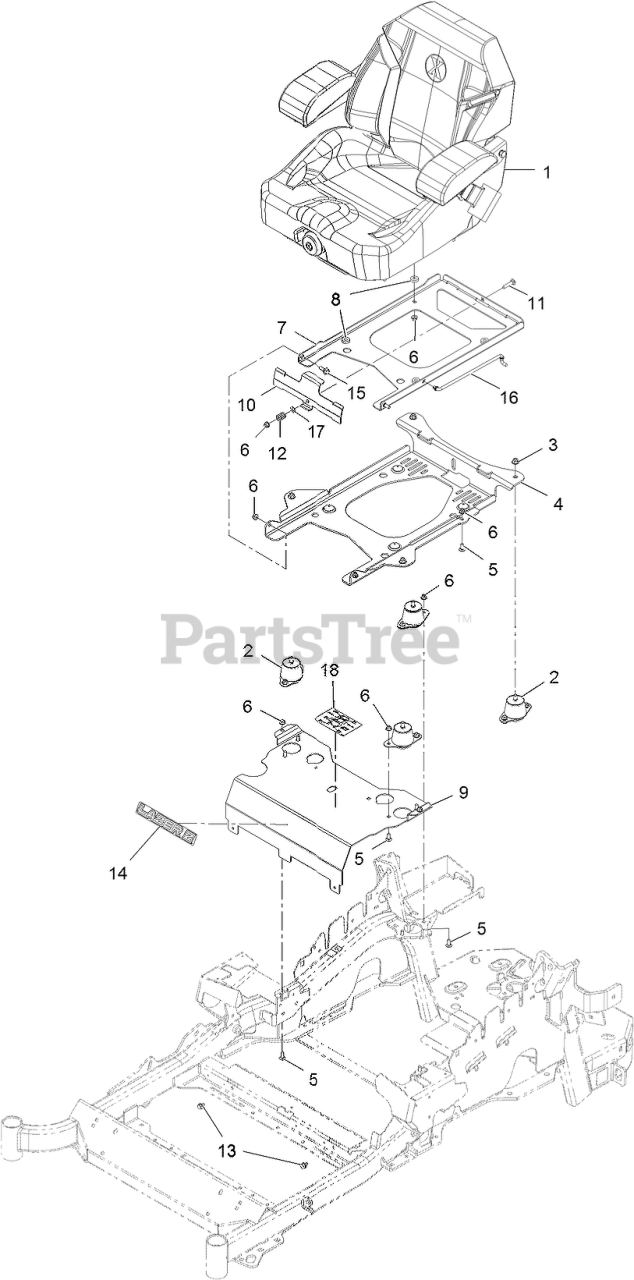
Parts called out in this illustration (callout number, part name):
1	KIT-SUSPENSION SEAT
2	ISOLATOR-SEAT
3	NUT-HF, NI
4	PLATE-TILT, SEAT SUPPORT
5	SCREW-CARR
6	NUT-HF, NI
7	PLATE-FRAME, SEAT
9	Panel-Front, Seat Mount
10	PLATE-LATCH, SEAT
11	BOLT-CARR
12	SPRING-COMPRESSION
14	DECAL, LAZER MODEL
15	SCREW-SHOULDER
16	ROD-PROP
17	WASHER-PLAIN
18	DECAL-SERVICE AID
